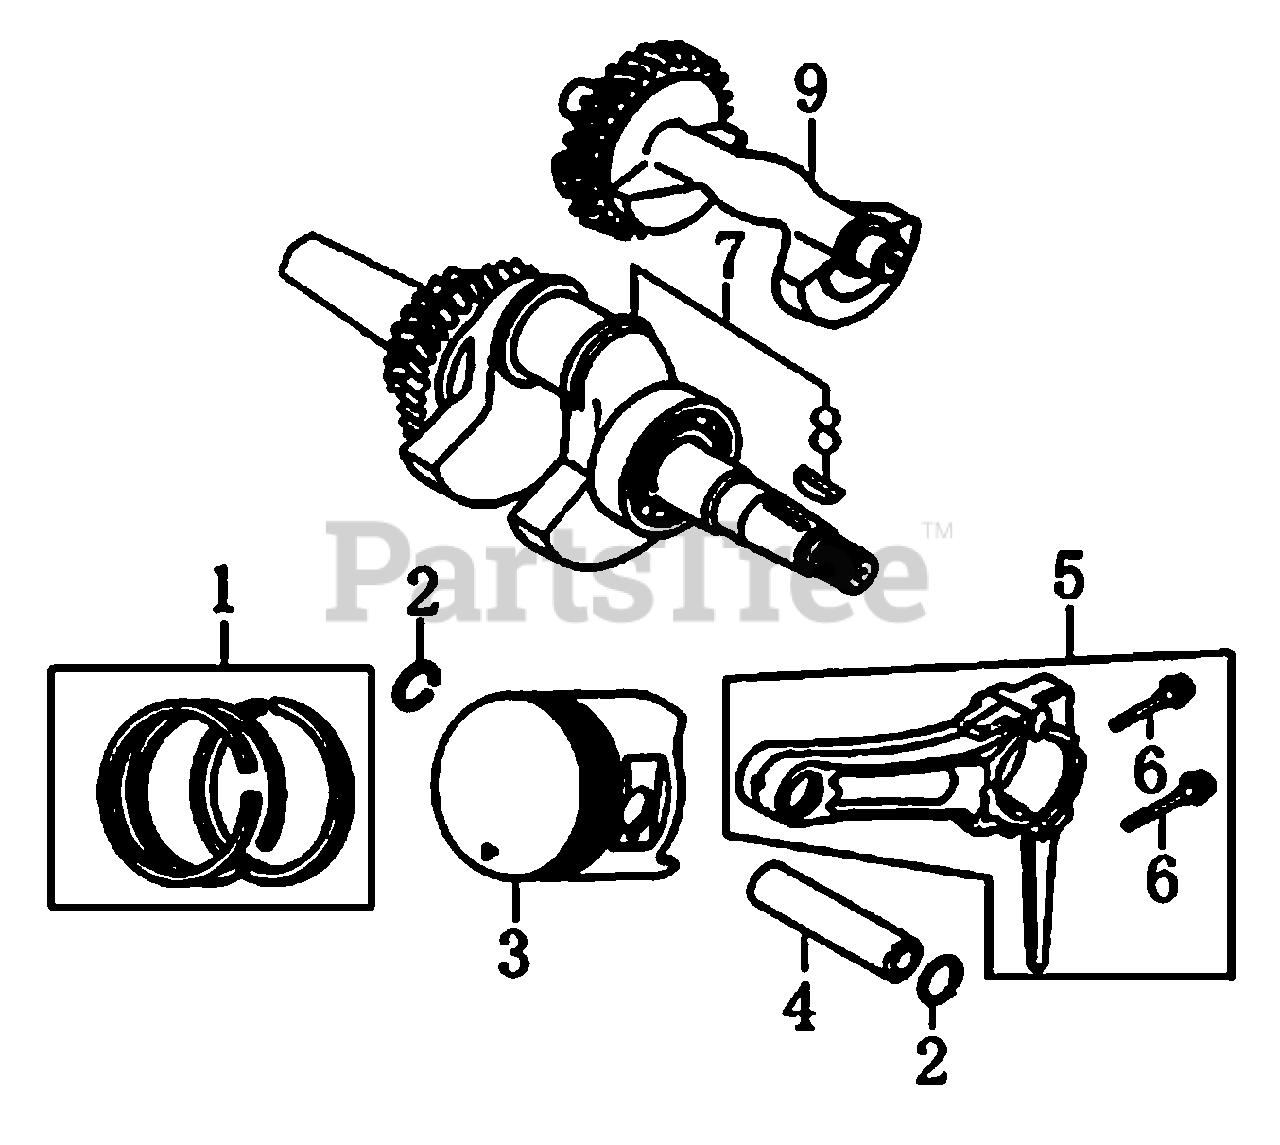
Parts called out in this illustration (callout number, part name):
1	RING SET, PISTON
2	CLIP, PISTON PIN
4	PIN, PISTON
5	CONNECTING ROD ASSY
6	BOLT, CONNECTING ROD
7	CRANKSHAFT ASSY
8	KEY, SPECIAL WOODRUFF
9	WEIGHT, BALANCER
